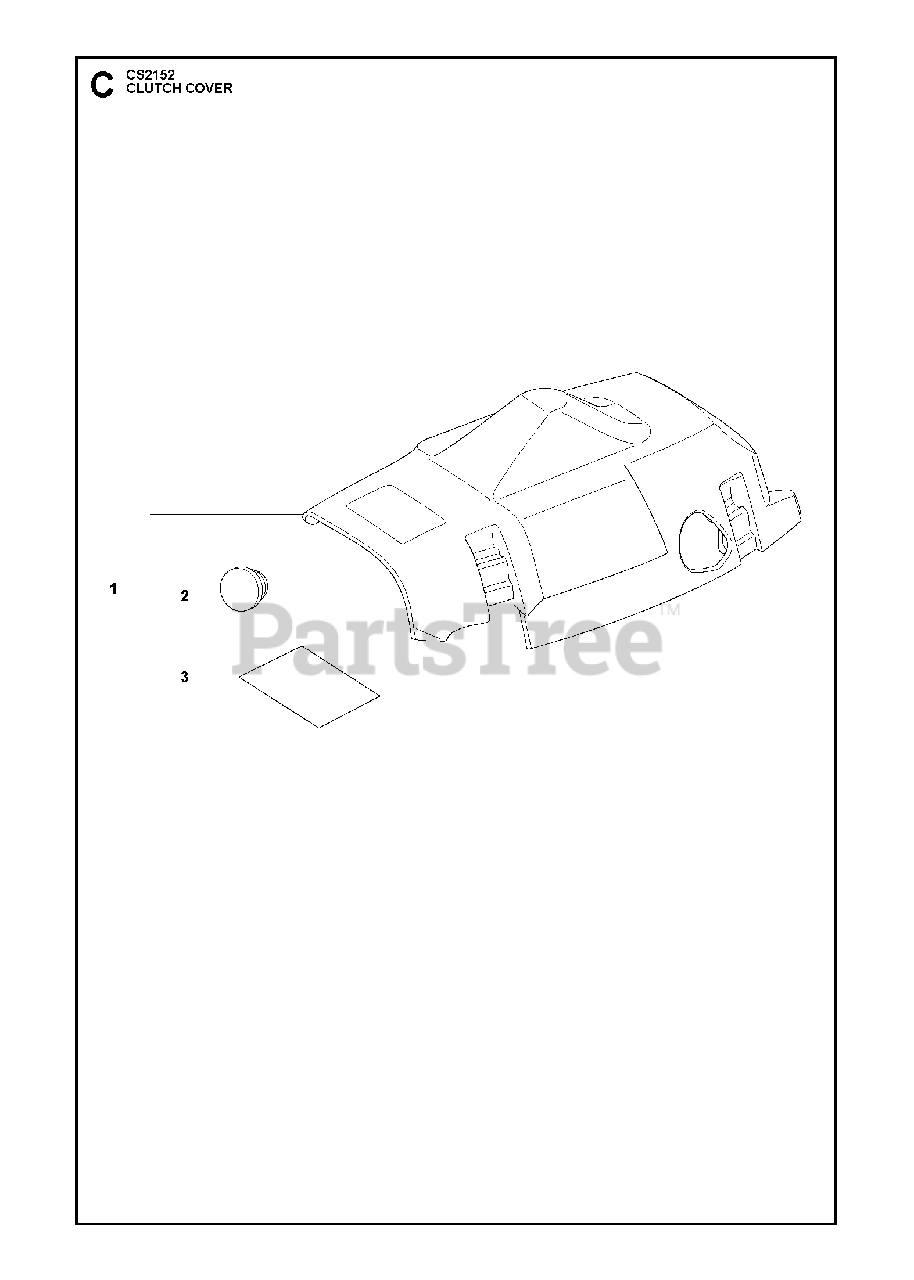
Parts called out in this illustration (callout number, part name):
1	CYLINDER COVER ASSY
2	PLUG
3	INSULATING FOIL/CYLINDER COVER
